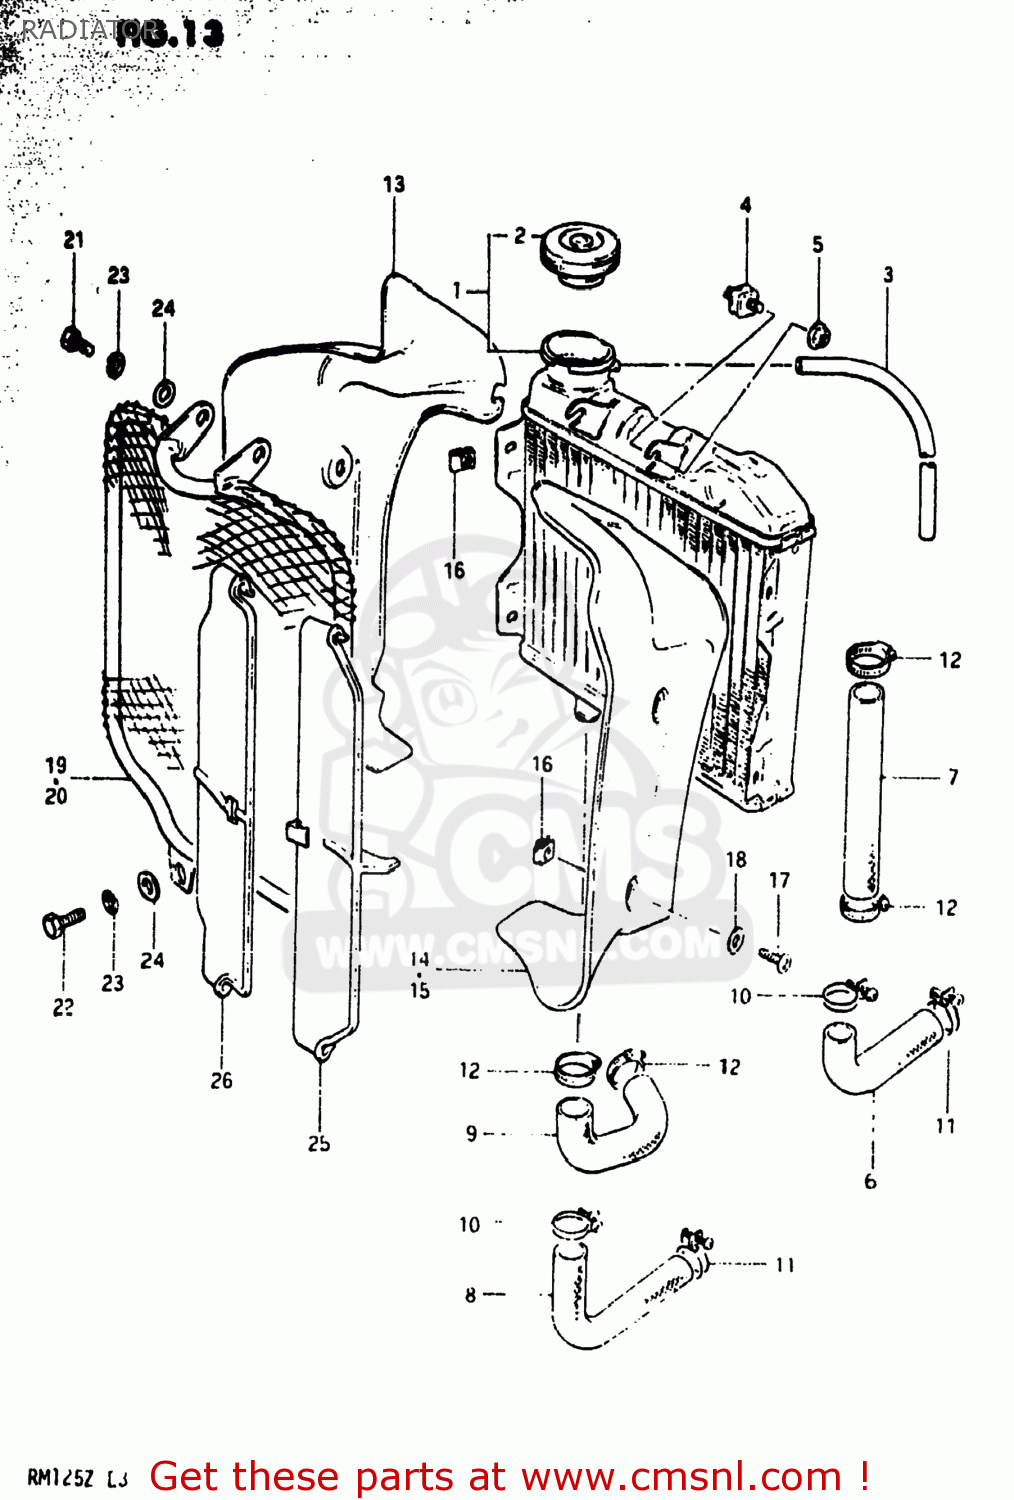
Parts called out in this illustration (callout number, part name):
1	RADIATOR ASSEMBLY,WATER
2	CAP,RADIATOR
3	HOSE,BREATHER
4	CUSHION,RADIATOR
5	NUT
6	HOSE,RADIATOR INLET
7	HOSE,RADIATOR
8	HOSE,RADIATOR OUTLET
9	HOSE,RADIATOR OUTLET
10	CLAMP
11	CLAMP
12	CLAMP
13	COVER,RADIATOR,R
14	COVER,RADIATOR,LEFT
15	COVER,RADIATOR,L
16	PLATE,RADIATOR COVER F
17	SCREW
18	WASHER
19	BUMPER,RADIATOR
20	BUMPER,RADIATOR
21	BOLT
22	BOLT 8X16
23	LOCK WASHER
24	WASHER
25	LOUVER,RADIATOR MUD GUARD
26	LOUVER, MUDGUARD INNER
